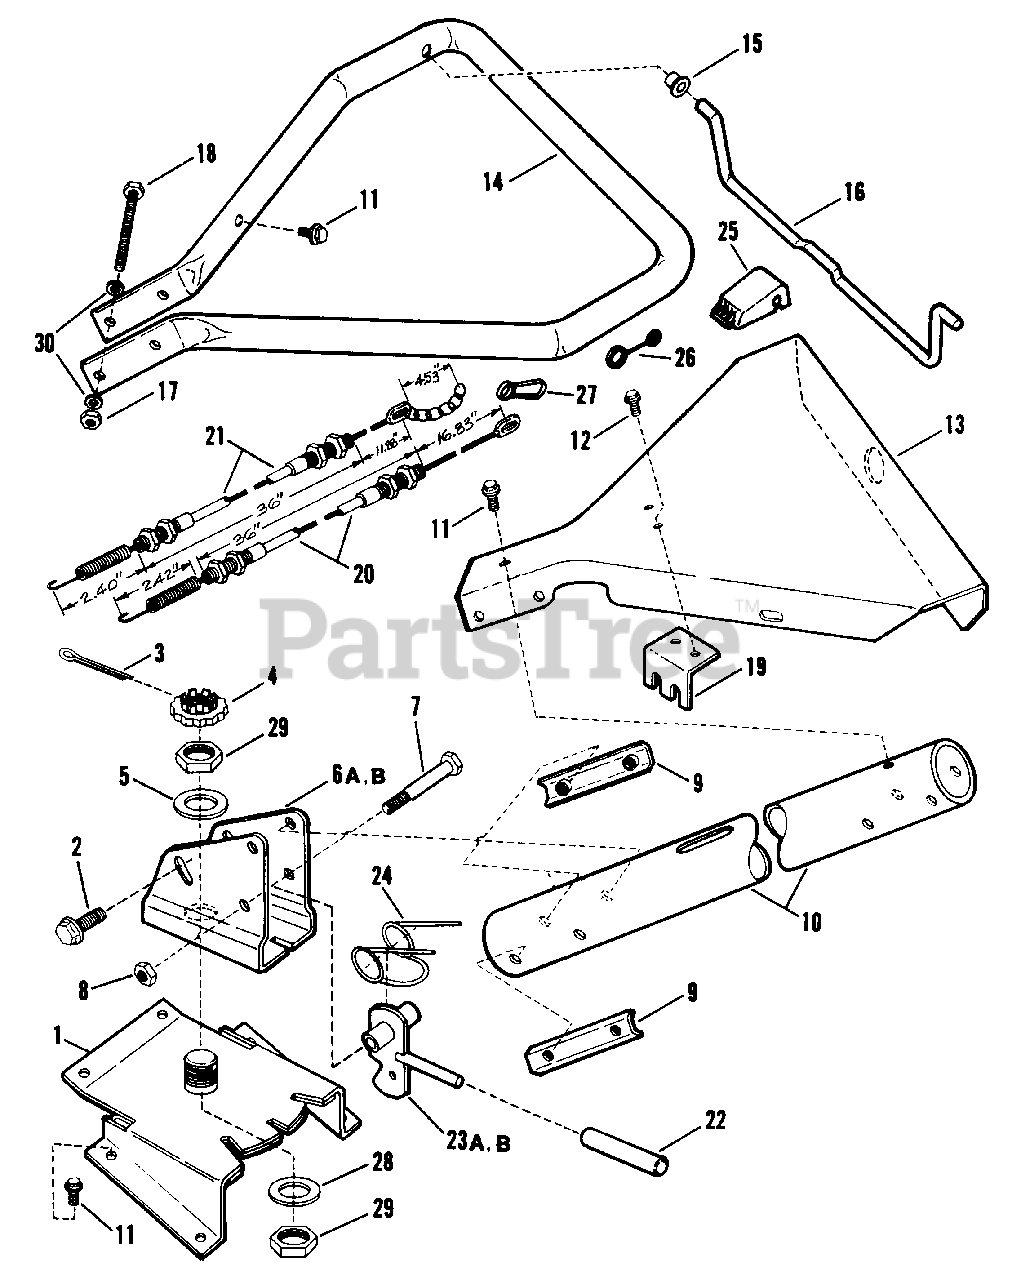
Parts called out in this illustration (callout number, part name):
1	BRACKET Latch
2	BOLT, 3/8-16 x 3/4" Hex Flange Lock
3	PIN, 5/32 x 1-1/4" Cotter
4	RETAINER, Nut Locking
5	WASHER, 13/16" Flat
6A	BRACKET, Handle
6B	(NLA) BRACKET, Handle
7	SCREW, 3/8-24 x 1/2" Hex Head Cap
8	NUT, 3/8-24 Hex Center Lock
9	PLATE, Tap
10	TUBE, Handle Bar Support
11	SCREW, 5/16-18 x 1/2" Hex Washer Self-Tap
12	SCREW, 1/4-20 x 1/2" Hex Washer Self-Tap
13	PANEL (5 HP)
14	BAR, Handle
15	BUSHING
17	NUT, 5/16-18 Hex Center Lock
18	SCREW, 5/16-18 x 3" Hex Head Cap, Grade 5
19	BRACKET
20	CABLE., Traction Control
21	CABLE, Tine Control
22	GRIP, Handle
23A	LATCH
23B	LATCH
24	SPRING
25	CLIP, Cable
26	LINK, Wire
27	CLIP-Snap
28	WASHER, 3/4" I.D. Flat
29	NUT, 3/4-16 Hex Jam Lock
30	WASHER, 5/16 SAE Flat
